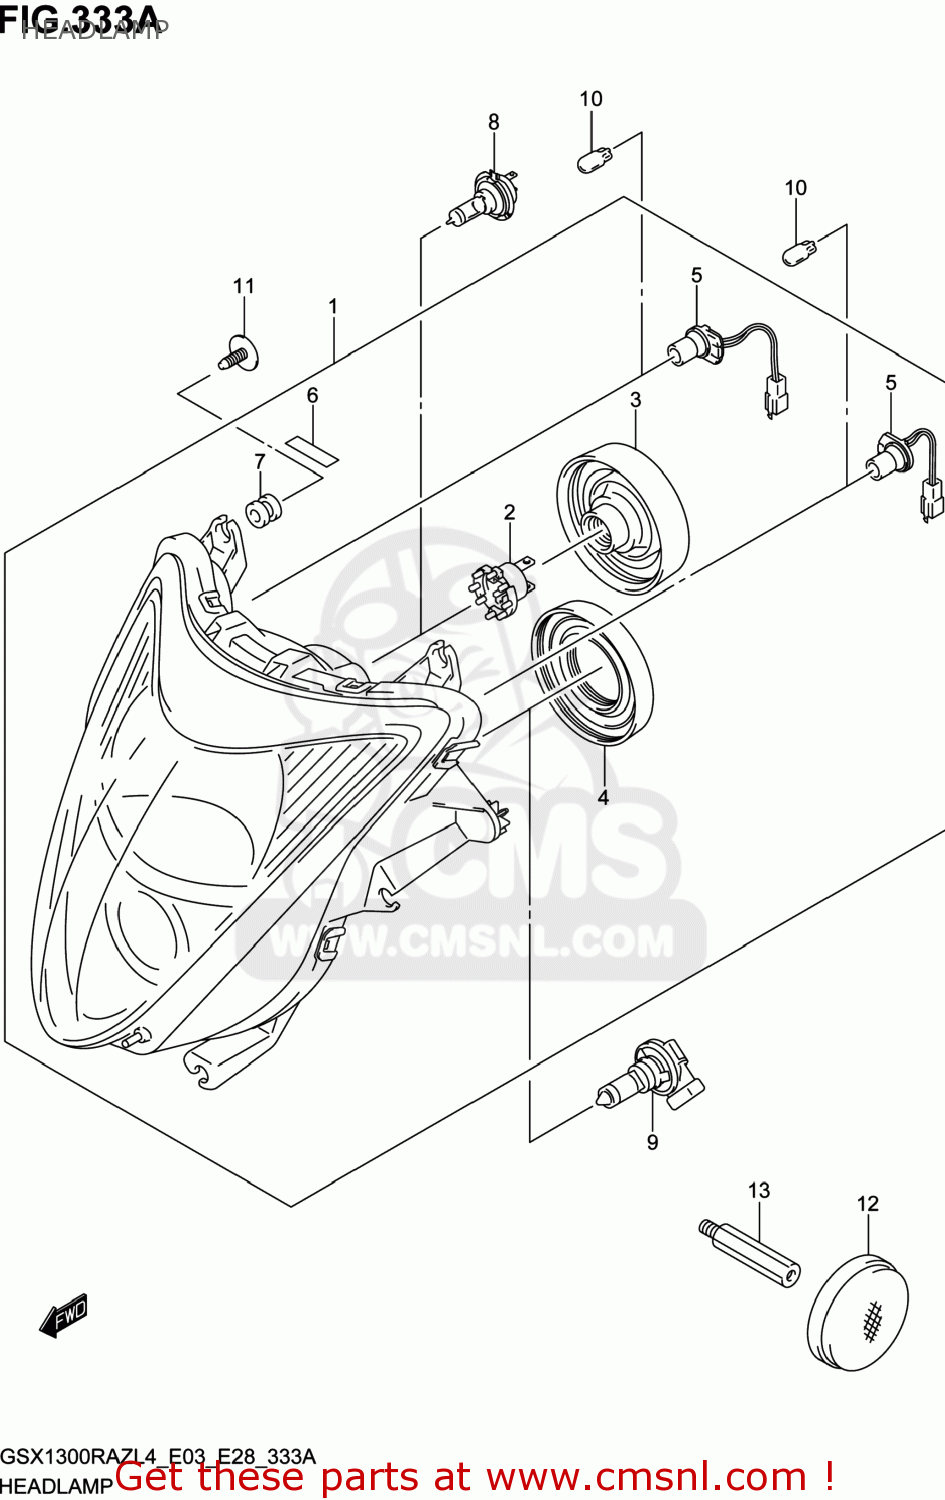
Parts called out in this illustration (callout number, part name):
1	HEADLAMP ASSY
2	ADAPTER ASSY
3	COVER
4	COVER
5	CORD ASSY
6	TAPE,FR TURNSIGNAL
7	CUSHION
8	BULB(12V55W/H7/PX26D/PHILIPS)
9	BULB(12V65W,H9)
10	BULB(12V5W)
11	SCREW(5X15)
12	REFLEX REFLECTOR ASSY,FR SIDE
13	BOLT
